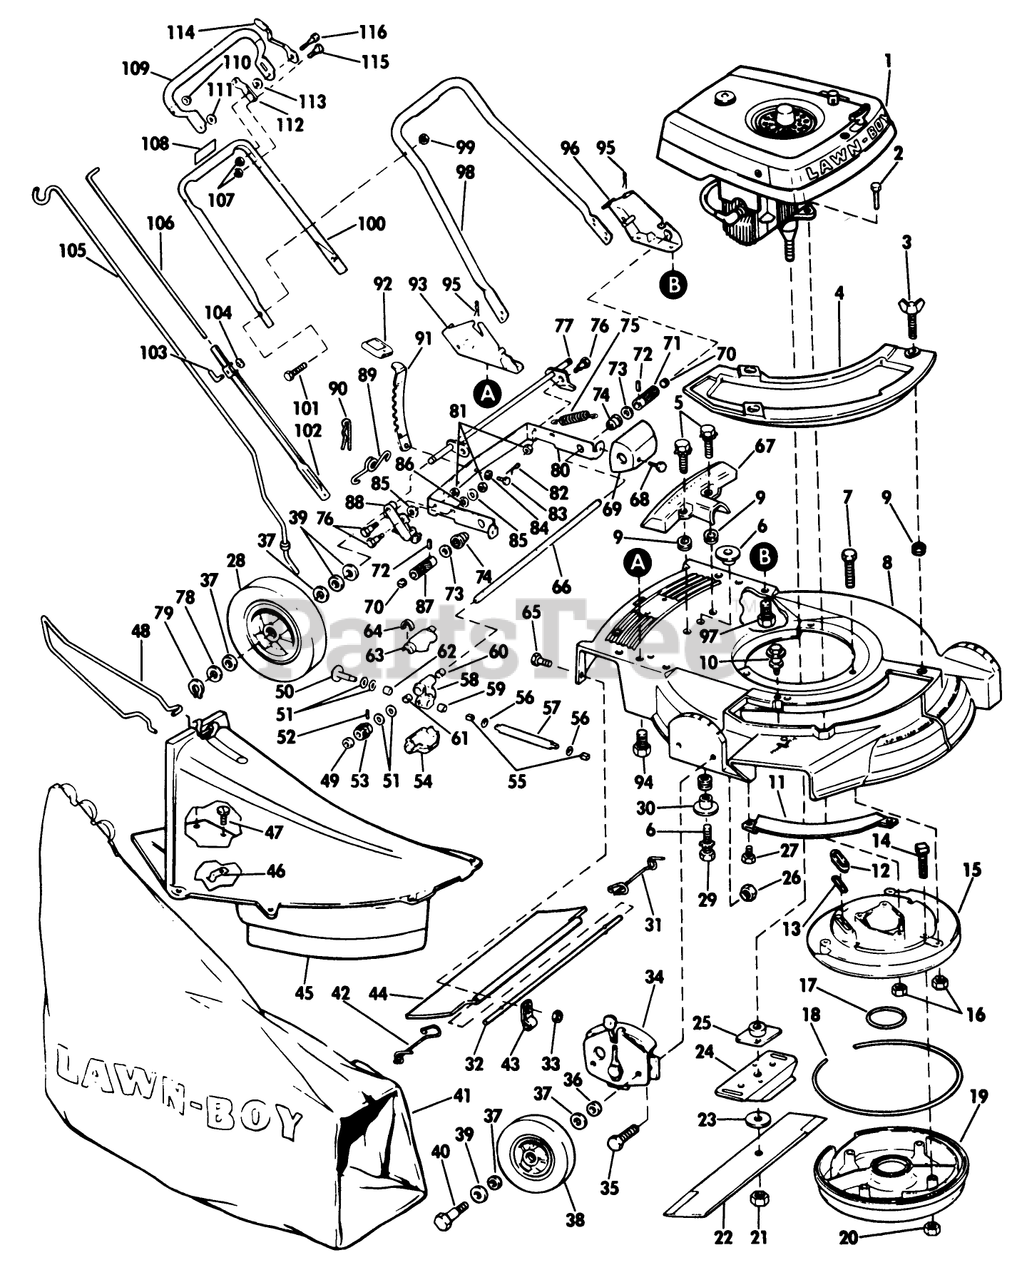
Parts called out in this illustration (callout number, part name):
2	BOLT F
3	WING SCREW LAWRE
5	SCREW SEMS TRM HEX HD
6	SPACER ECK PRES
7	SCREW V
11	BAR-TOE
12	SLEEVE
13	GASKET S
14	SCREW
16	NUT-LOCK F
18	Gasket Muffler (outside)
20	LOCKNUT E
21	NUT-BLADE
23	WASHER
25	PLATE AND COLLAR ASM
26	NUT
30	GROMMET
31	SPRIG T/SHLD ASOC
32	ROD 21" ADVANCE
36	WASHER WROUGHT
37	WASHER
39	SPACER
40	BOLT WHEEL
41	89802 LB WHOLE GOODS
42	SPRING;TRAILING SHIELD RH
43	CLAMP ROD KMC
49	WASHER
51	THRUST WASHER
52	ROLL PIN
55	BUSHING
56	O Ring
62	NEEDLE BEARING
63	GEAR COVER UPPER
67	COVER
69	GUARD
70	GREASE PLUG
72	PIN
75	SPRING
76	BOLT RB&W
78	SPACER
79	RET RING
81	STOP NUT
83	PIN
84	WASHER SPRING LAR
85	WASHER S
89	SPRING N.A.S
91	LEVER
92	KNOB
94	SCREW
95	HAIR PIN
97	SCREW
101	Screw
105	ROD GRASSBAG
106	ROD CONTROL
111	WASHER M
114	KNOB & SPRING
116	BOLT RB&W
